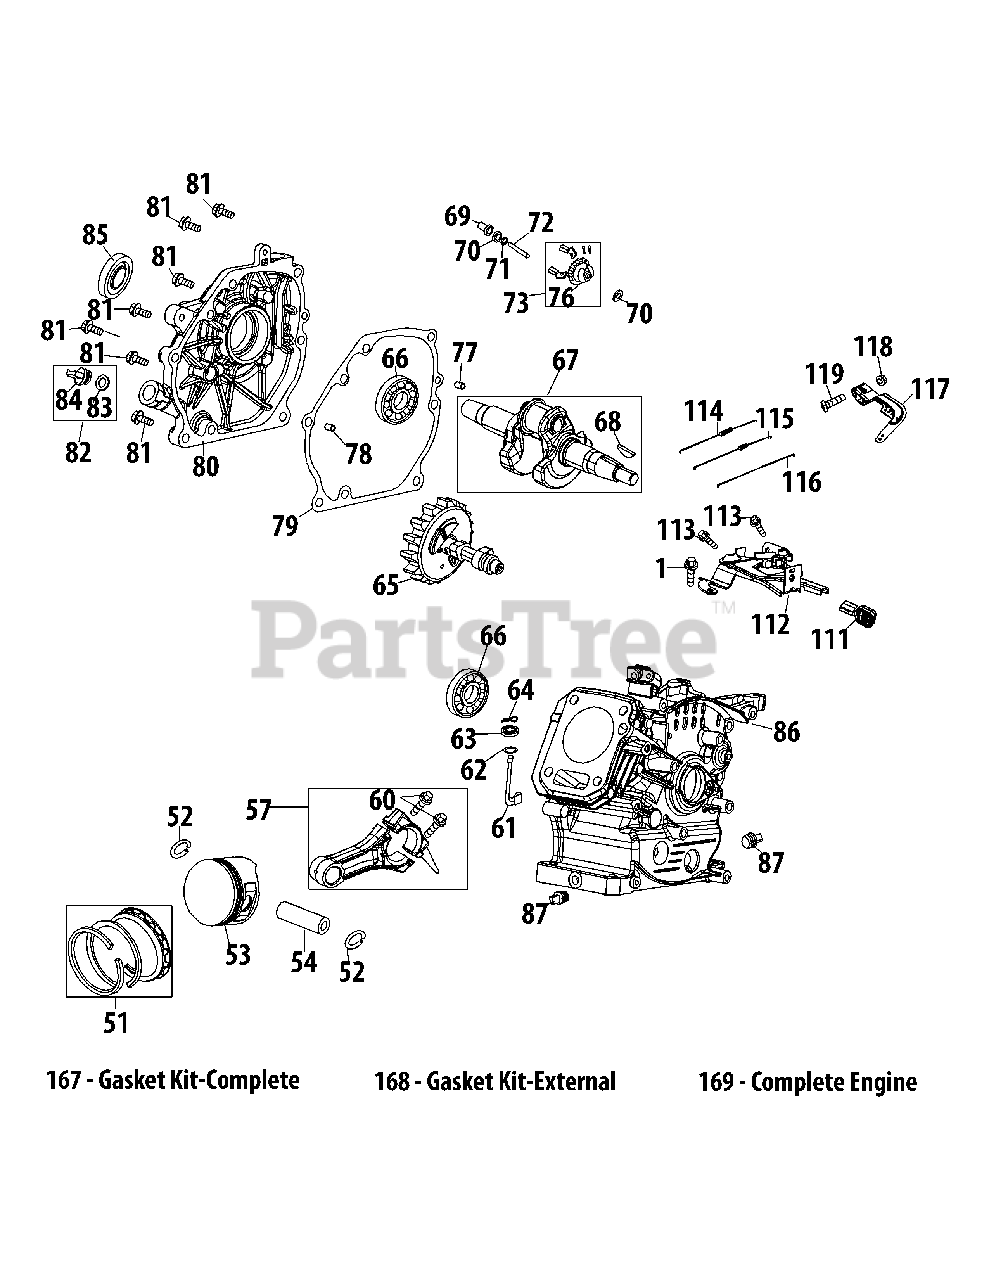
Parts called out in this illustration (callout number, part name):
1	Bolt M6×16
51	Connecting Rod Assembly
52	PISTON PIN SNAP RING
53	Piston
54	PISTON PIN
57	CONNECTING ROD ASSEMBLY
60	Connecting Rod Bolt
61	Governor Arm
62	Washer 5.2×1.9
63	Governor Seal
64	Cotter Pin
65	CAMSHAFT ASSEMBLY
66	Radial Ball Bearing
67	Crankshaft Kit
68	Woodruff Key
69	Governor Cup
70	Washer 6.2×0.6×15
72	Governor Shaft
73	Governor B0Dy
76	Governor Gear
77	Dowel Pin 7×14
78	Dowel Pin 9×14
79	Crankcase Cover Gasket
80	Crankcase Cover
81	Bolt M8×32
82	Oil Fill Plug Asm
83	O-RING 15.8 x 2.5
84	Oil Plug
85	OIL SEAL 25 x 41.25 x 6
86	Crankcase Kit
86	Crankcase Cover Kit
86	Shortblock Assembly
87	Oil Drain Plug
111	Throttle Control Knob
112	Primer Bracket
113	Bolt M6×12
114	Governor Spring
115	Throttle Linkage Spring
116	THROTTLE LINKAGE
117	Governor Arm
118	Nut M6
119	Governor Arm Bolt
167	Gasket Kit-Complete
168	Gasket Kit-External
169	Complete Engine
